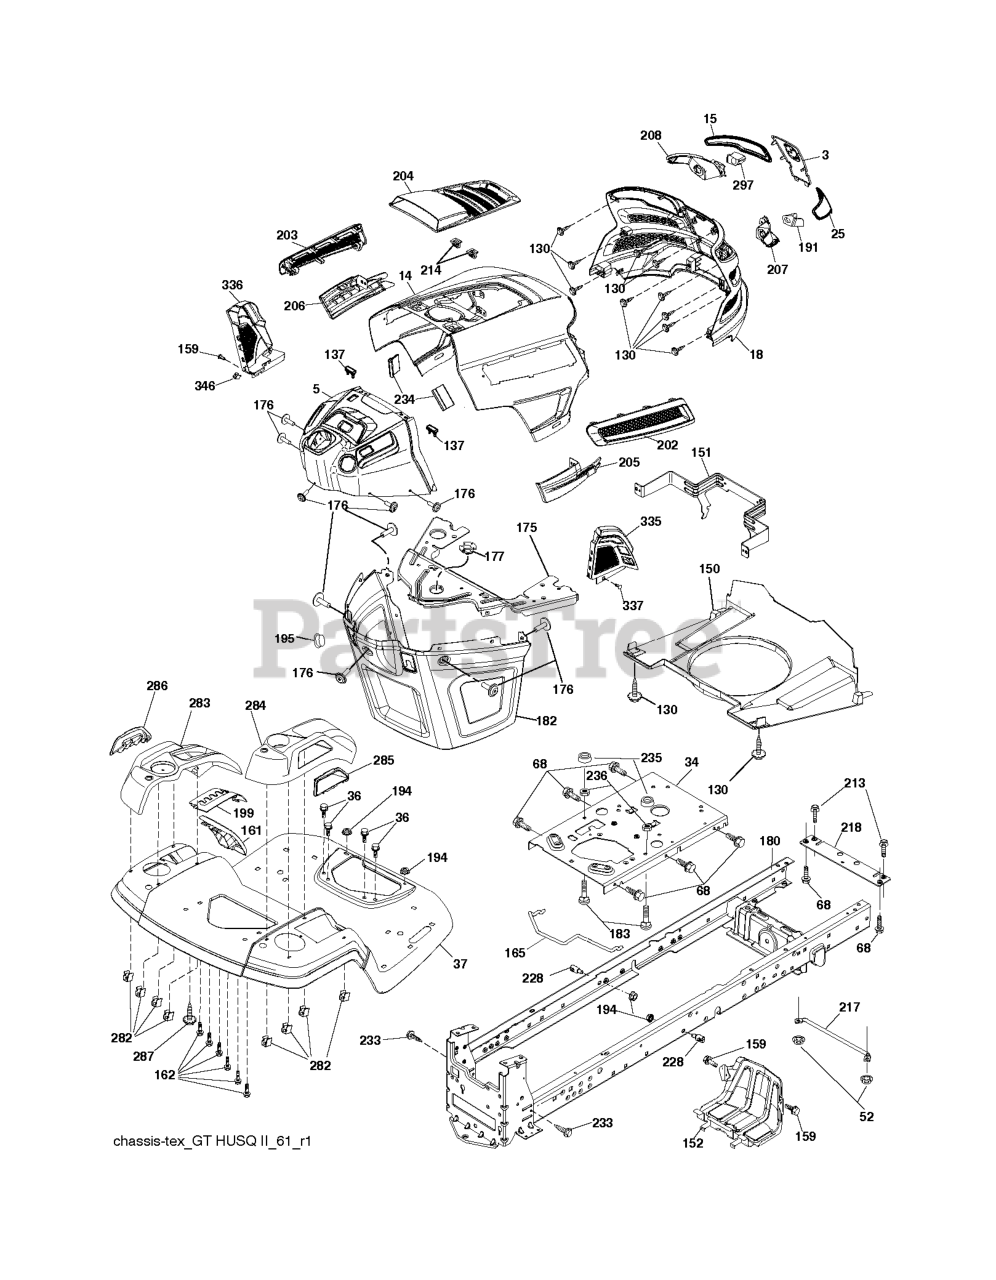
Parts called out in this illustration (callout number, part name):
3	APPLIQUE.SUBASM.GT.HUSQ.II
5	DASH.UPP.GT2.SM.PTO.MCHOKE
14	HOOD.ASM.HUSQVARNA.GT.TEX.ORAN
15	LENS.HEADLIGHT.LH.GTII.2011
18	GRILLE.SUBASM.GT.HUSQ.II
25	LENS.HEADLIGHT.RH.GTII.2011
34	PLATE.ENGINE.WELDED.CHASSIS
36	SCREW 5/16"
37	FENDER.TLT.FS.W/CPH/FW/RSF.668
52	LOCKNUT
68	SCREW LT
130	SCREW.#10 X 0.750.BOS
137	BUMPER DASH
150	AIR.DUCT.GTV.BLACK
151	BRACKET.PIVOT.HOOD.GT.HUSQ.II
152	SHIELD.BROWNING.PNT.GT.V2
159	SCREW, 3/8-16X3/4
161	WINDOW.FUEL.LT.HUSQ.TEX.498
162	SCREW.HI-LO.CONSOLE
165	SUPPORT.TANK.REAR.W/TEX
175	PLATE.CROSSMEMBER.HUSQ
176	SCREW.#10-24X5/8.RN.QU
177	BUSHING, STEERING
180	CHASSIS
182	DASH.LOWER.COMMON.12V.ADAPTOR
183	BOLT.5/16-18X1-1/4 FULL THD
191	INSERT.REFLECTIVE.RH.HUSQ.GTII
194	NUT LOCK HEX FLANGE 5/16-18
195	PLUG.HOLE.DASH.LOWER.12V.BLK
199	PLATE.DECK.LIFT.HUSQ.LT
202	VENT.SIDE.RH.GT.HUSQ.II.
203	VENT.SIDE.LH.GT.HUSQ.II.498
204	VENT.TOP.HUSQ.GT2
205	SIDE.TRIM.RH.GT.HUSQ.II
206	SIDE.TRIM.LH.GT.HUSQ.II.GRAY
207	BEZEL LIGHT.RH.GT.II.MYLAR
208	BEZEL LIGHT.LH.GT.II.MYLAR
213	BOLT
214	CLIP.RETAINER.TINNER.
217	ROD.PIVOT.HOOD
218	X-PIECE.HOOD.STOP.NON/
228	STUD.FASTNER.W/ANTI-ROTATE
233	BOLT.SHOULDER
234	BUMPER.HOOD.TEX.HUSQVARNA
235	SPACER FENDER
236	NUT.CENTERLOCK.5/16-
282	CLIP.RETAINER.CONSOLE.LT.HUSQ
283	CONSOLE.DECK.LIFT.R.SDFL.HUSQ
284	CONCOLE.CNTRL.PDL.HUSQ.LT.498
285	CONSOLE INSERT RH
286	CONSOLE.INSRT.LH.HUSQ.LT.BLACK
287	SCREW 1/4X20
297	INSERT.REFLECTIVE.LH.HUSQ.GTII
335	COVER.RH.CLOSE.OUT.BLACK
336	COVER-LH.LOWER.DASH.GT2.BLACK
337	CLIP.XMAS.TREE.ITW.2622-00
346	CLIP,INSULATOR
